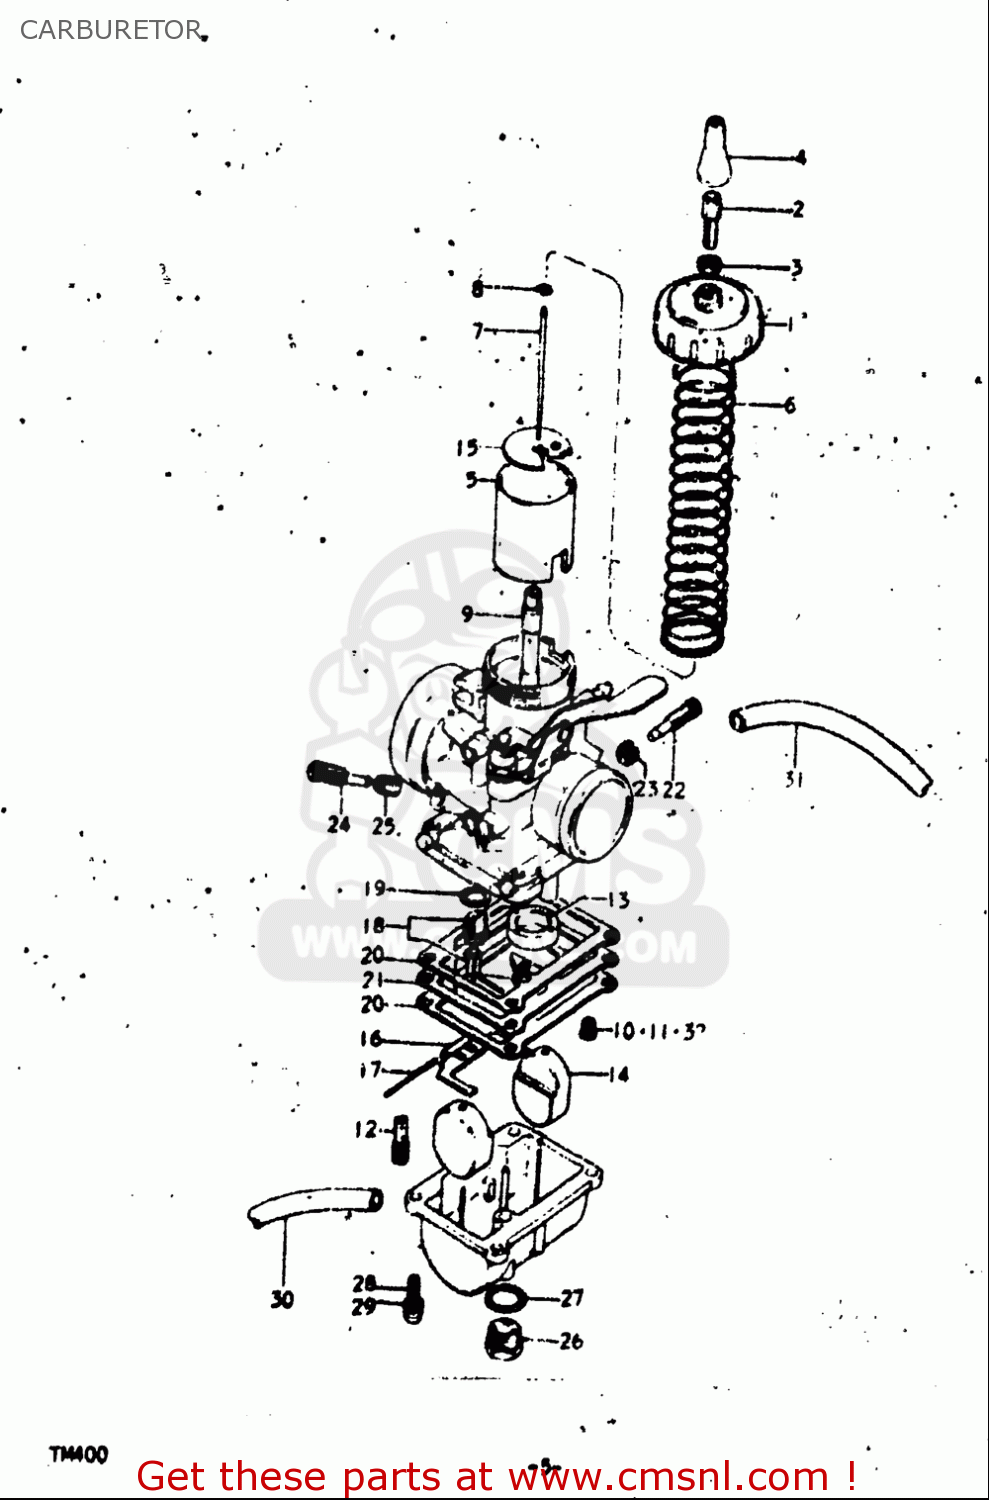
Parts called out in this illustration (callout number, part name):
2	ADJUSTER,CABLE
3	NUT
4	CAP
8	CLIP
10	JET,MAIN(240)
11	JET,MAIN(250)
12	JET,PILOT(35)
14	FLOAT
18	VALVE ASSY,NEEDLE
19	GASKET,MAIN JET HOLDER (NAS)
20	GASKET,FLOAT CAHMBER (NAS)
23	NUT, STOP SCREW
24	SCREW,PILOT AIR
25	SPRING
27	GASKET,DRAIN PLUG
28	SCREW
29	WASHER,LOCK
30	HOSE(3.5X6.5X600)
31	HOSE(3.5X6.5X600)
32	JET,MAIN(290)
